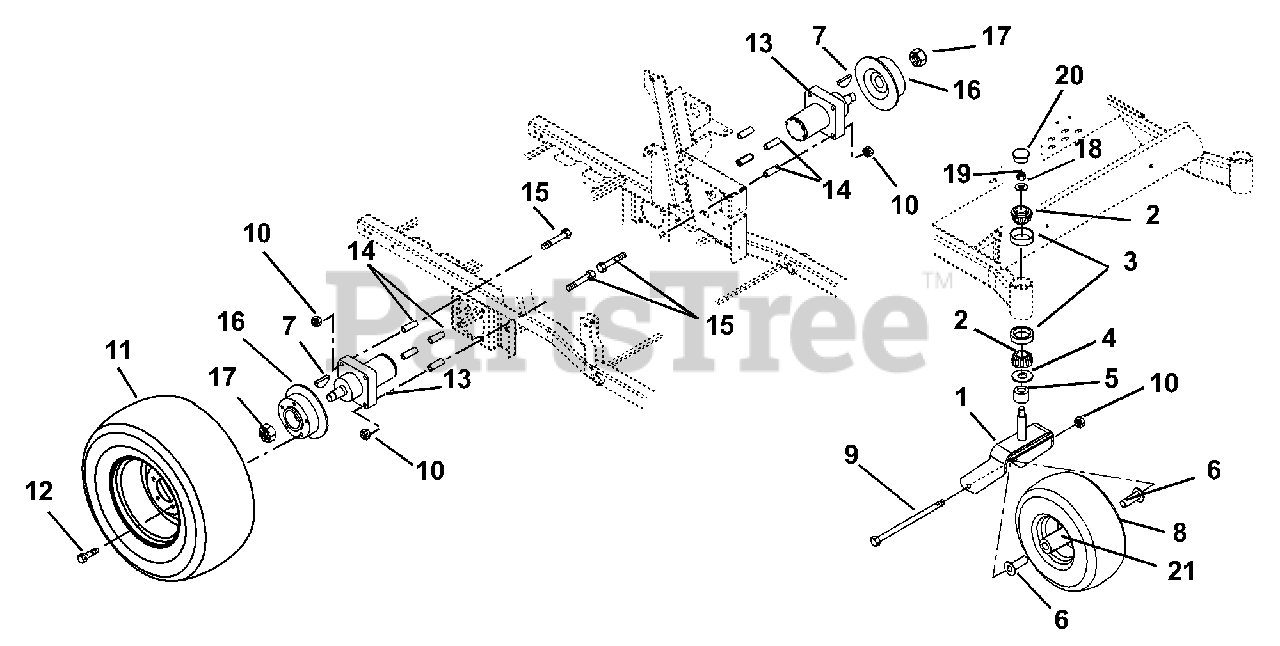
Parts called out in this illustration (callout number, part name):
1	Fork
2	Bearing, Cone with Grease
3	Bearing, Cup 1.98 x .420
4	Bearing Seal 1.5 x 2 x .18
5	Spacer, PM, 1.03 I.D. x 1.5 O.D. x .375
6	Spacer, Wheel
7	Key, Woodruff .31 x 1.00
8	Wheel/Tire Assembly
8	Tire, 15 x 6-6
9	Bolt, Hex .50-13 x 9.00 Grade 5
10	Nut, Locking Top Flange .50-13
11	Tire 23 x 10.50
11	Wheel, Tire 23 x 10.50 - 12 Multi-Trac
12	Bolt, Lug Grade 8 .50-20 UNF x 1.38 Long 60 Degree
13	Hydraulic Wheel Motor
14	Bushing, Sleeve .513 x .748 x 2.13
15	Bolt, Wheel Motor .50-13 x 5.00
16	Hub and Disc
17	Nut, Lock Jam Patch
18	Washer, Flat, Steel .812 x 1.50 x .135
19	Nut, Jam Center Lock .75-16
20	Cap, Dust
21	Bearing, 25mm I.D. x 52mm OD x 15mm
